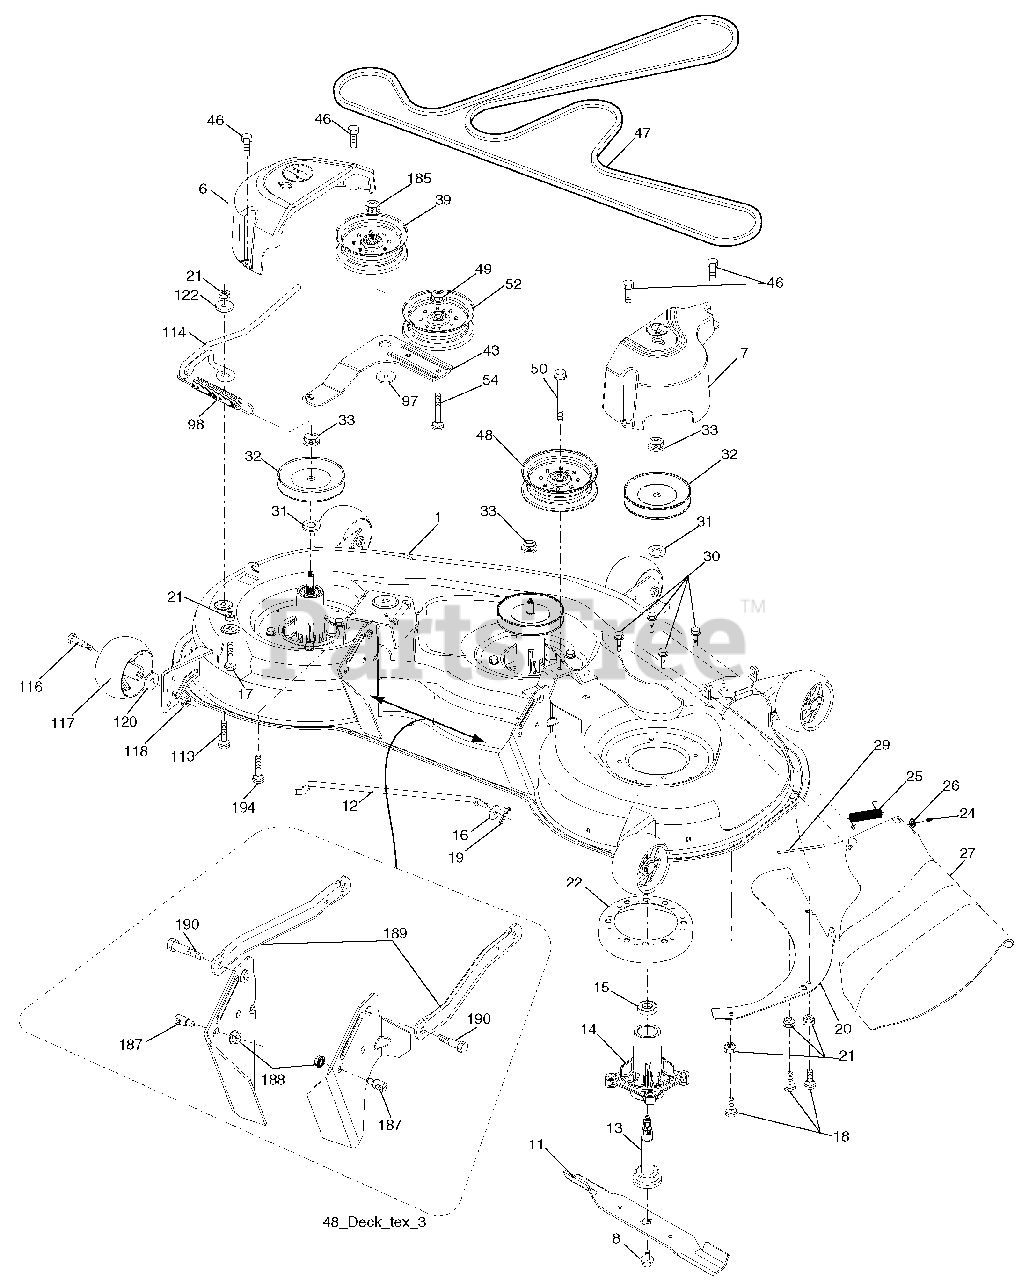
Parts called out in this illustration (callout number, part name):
1	Deck Weldment Mower
6	Cover Mandrel LH
7	Cover Mandrel RH
8	Bolt 7/16 Asm. Blade
11	Blade High Lift
11	Blade Mulching
12	Rod Anti-Sway
13	Shaft Asm. w/Lower Bearing
14	Housing, Mandrel
15	Bearing, Ball, Mandrel
16	Washer 13/23 x 13/16 x 1 2 Ga.
17	Bolt Carr. 5/16-18 x 5/8
18	Bolt RdHd 5/16-18 unc x 5/8
19	Pin Cotter 5/16 Bowtie Lock
20	Baffle Vortex
21	Nut, Crownlock 5/16-18 unc
22	Stripper Mandrel Deck
24	Cap Sleeve
25	Spring, Torsion
26	Nut, Push
27	Defl ector Shield
29	Rod, Hinge
30	Screw, Thdroll Washer Head
31	Washer, Spacer Mower Vented
32	Pulley, Mandrel
33	Nut, Flg. Top Lock
39	Pulley, Idler, Stationary
43	Arm, Idler
46	Screw, Thdroll. 1/4-20 x 5/8
47	Belt Drive Deck
48	Pulley Idler Primary
49	Nut, Lock Flg. 3/8-16 unc
50	Screw 3/8-16 x 1-1/4 unc
52	Pulley Idler
54	Bolt Carriage 3/8-16 x 1-1/2 Gr.5
97	Washer Hardened
98	Spring Drive
113	Bolt Rdhd Sqnk 5/16-18 x 3/4
114	Rod Tension Relief
116	Bolt, Shoulder
117	Gauge Wheel
118	Nut 3/8-16 unc
120	Washer 13/32 x 1-1/4 x 12 Ga.
122	Bushing Tension Relief
185	Nut Lock Flange 7/16-14 Gr. 5
187	Stud Fastener w/"D" Anti-Rotation
188	Nut Lock Hex Flange
189	Arm Susp. Mower Rear
190	Bolt Shoulder
194	Bolt Carr Sqnk 3/8-16 x 2-1/4
194	Mandrel Asm. Service
194	Replacement Mower, Complete
